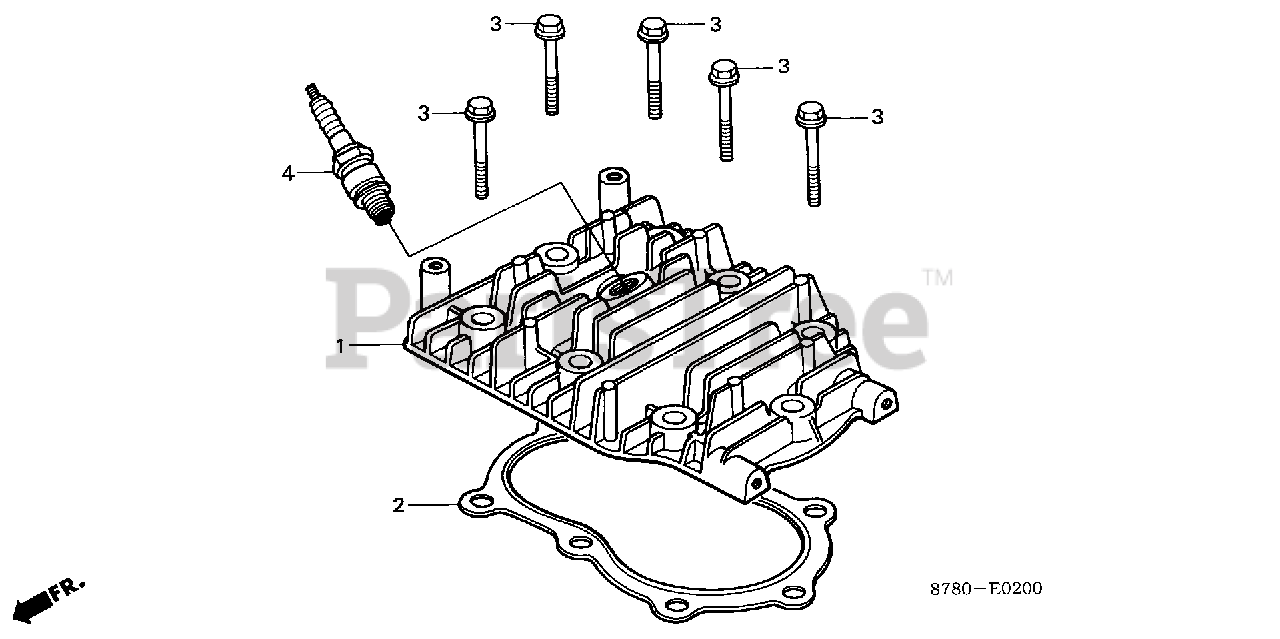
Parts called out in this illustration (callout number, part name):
1	CYLINDER HEAD
2	GASKET, CYLINDER HEAD (NOT AVAILABLE)
3	BOLT, FLANGE (8X40)
4	SPARK PLUG (B6HS) (NGK)
